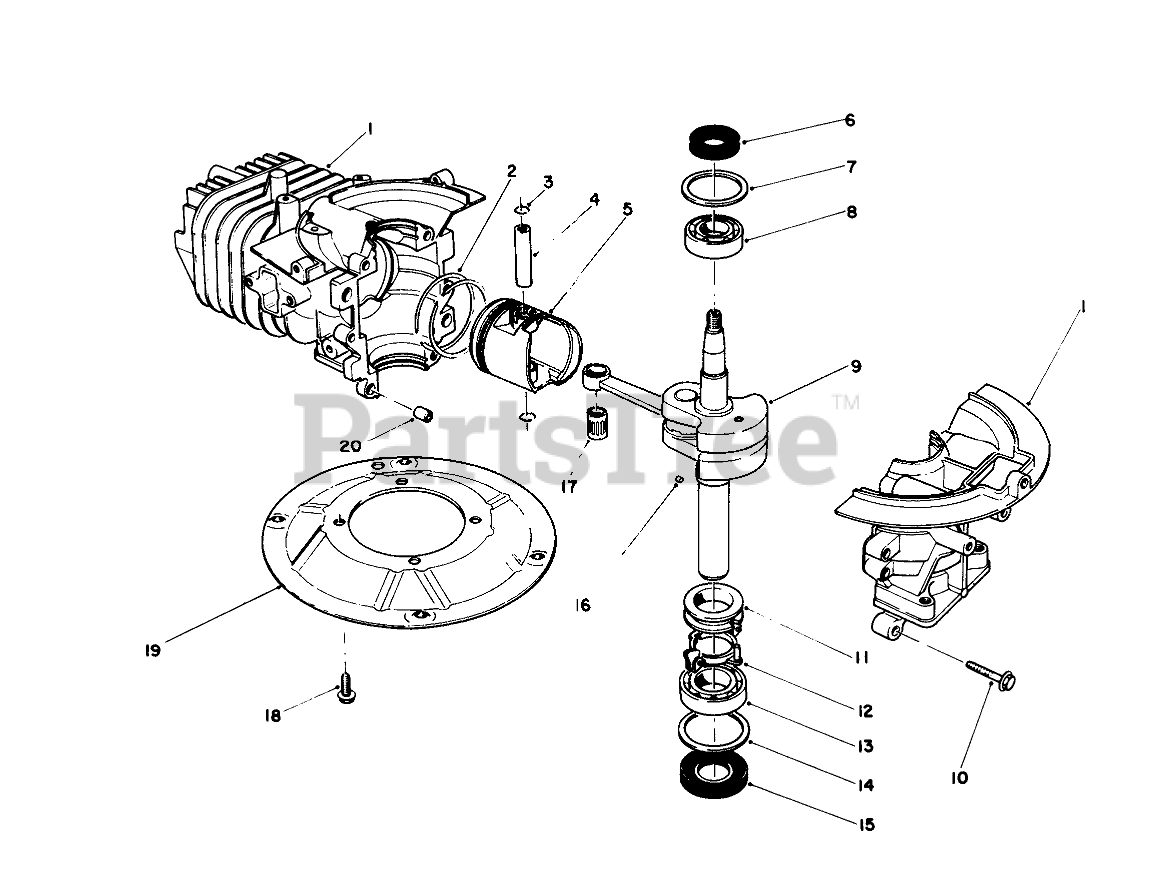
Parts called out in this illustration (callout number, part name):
1	CRANKCASE
2	RING SET
4	PIN-PISTON
5	Piston
6	OIL SEAL
7	WASHER-UPPER
8	BEARING-UPPER
9	Pin-Wrist
11	SPACER
12	BRACKET
13	LOWER BRG
14	WASHER-LOWER
15	SEAL-OIL
17	BEARING
19	PLATE-MOUNTING
